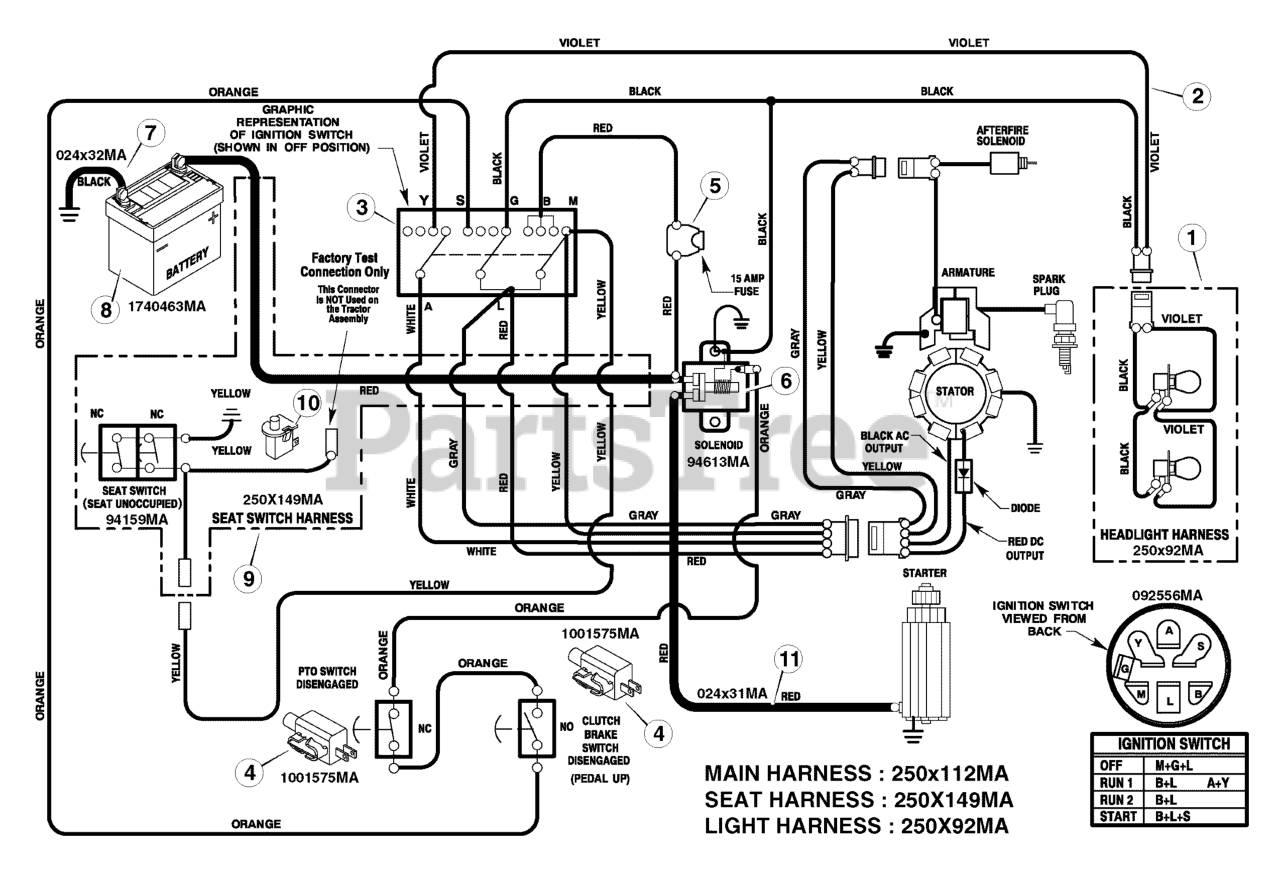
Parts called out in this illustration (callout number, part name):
1	HARNESS, Light Wire
2	HARNESS, Chassis Wire
3	SWITCH, Ignition
4	SWITCH, Limit
6	SOLENOID
7	CABLE, Battery Ground
9	HARNESS, Seat Switch Wire
10	SWITCH, Seat Sensor
